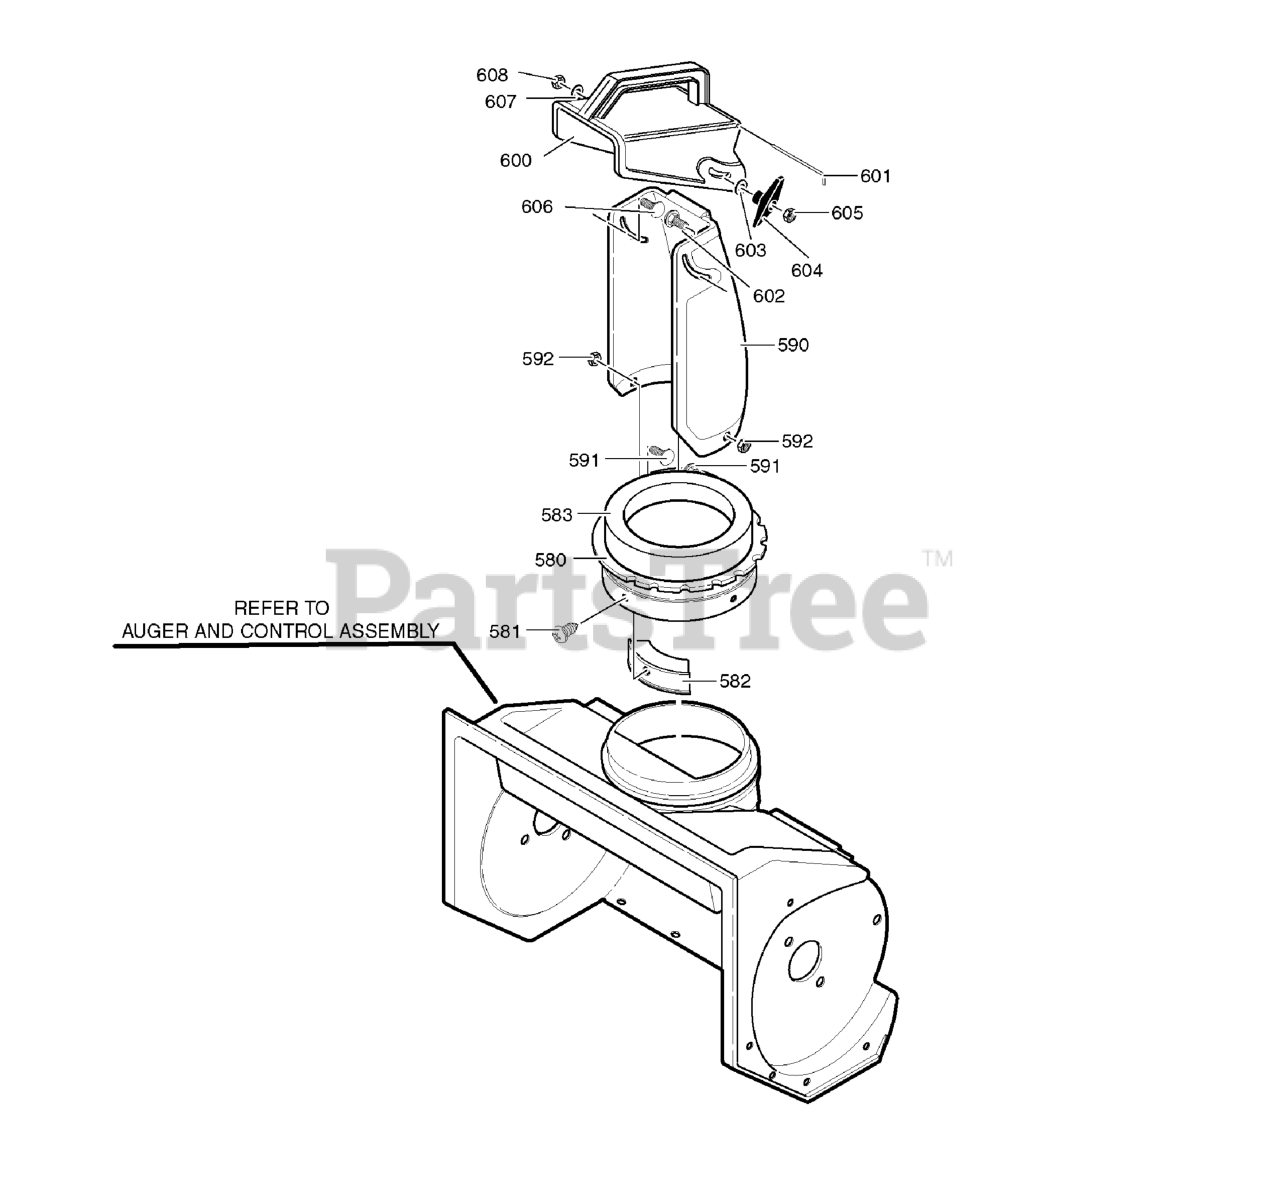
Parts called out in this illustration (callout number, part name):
580	RING, CHUTE
581	SCREW, #10 X .50
582	GUIDE, CHUTE
583	DONUT FOAM
590	CHUTE, DEFLECTOR LOWER
591	SCREW 1/4-20 X .50
592	NUT, 1/4-20
600	CHUTE DELFECTOR, UPPER
601	WIRE, CHUTE HINGE
602	BOLT, 5/16-18 X 1.25 CARRIAGE
603	WASHER, FLAT .349 X .69 X .066
604	KNOB, WING
605	NUT, 5/16-18
606	SCREW, 5/16-18 x 0.75
607	WASHER, FLAT .349 X .69 X .066
608	NUT, 5/16-18 HEX CONTROL LOCK
